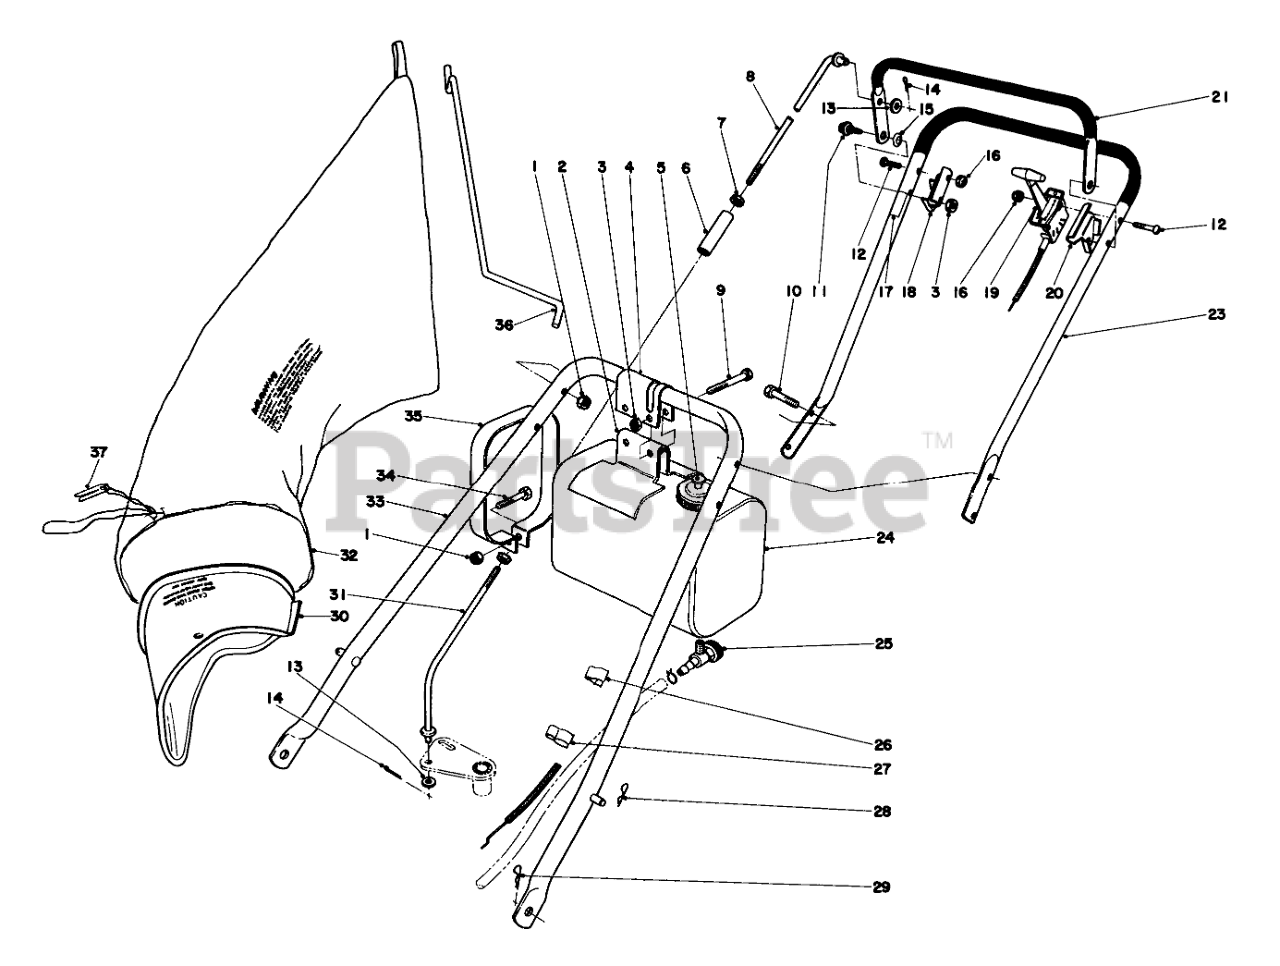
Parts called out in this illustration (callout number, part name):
1	NUT-LOCK
2	FUEL TANK BRACKET
3	Nut
4	Clamp
6	CONTROL ROD SLEEVE
7	NUT-KEPS
8	Control Rod
9	SCREW-HH
10	SCREW-HH
11	SCREW-SHOULDER
12	10-24X1-1/4 PAN HD MS
13	WASHER-PLAIN
14	PIN-COTTER
15	WASHER-SPRING
16	NUT-LOCK, NI
17	Decal
18	CONTROL BAIL BRACKET
20	Bracket-Control Bail
21	Control Bail
23	Handle & Grip Assembly
24	Tank
25	.125 ID SHUTOFF VALVE
26	Clamp
27	CLAMP
28	PIN-COTTER
29	PIN-COTTER, HAIR
30	BAG ATTACHMENT
31	CONTROL ROD
33	Lower Handle Assembly
34	SCREW-HH
35	TANK STRAP
37	BAG CORD FASTENER
